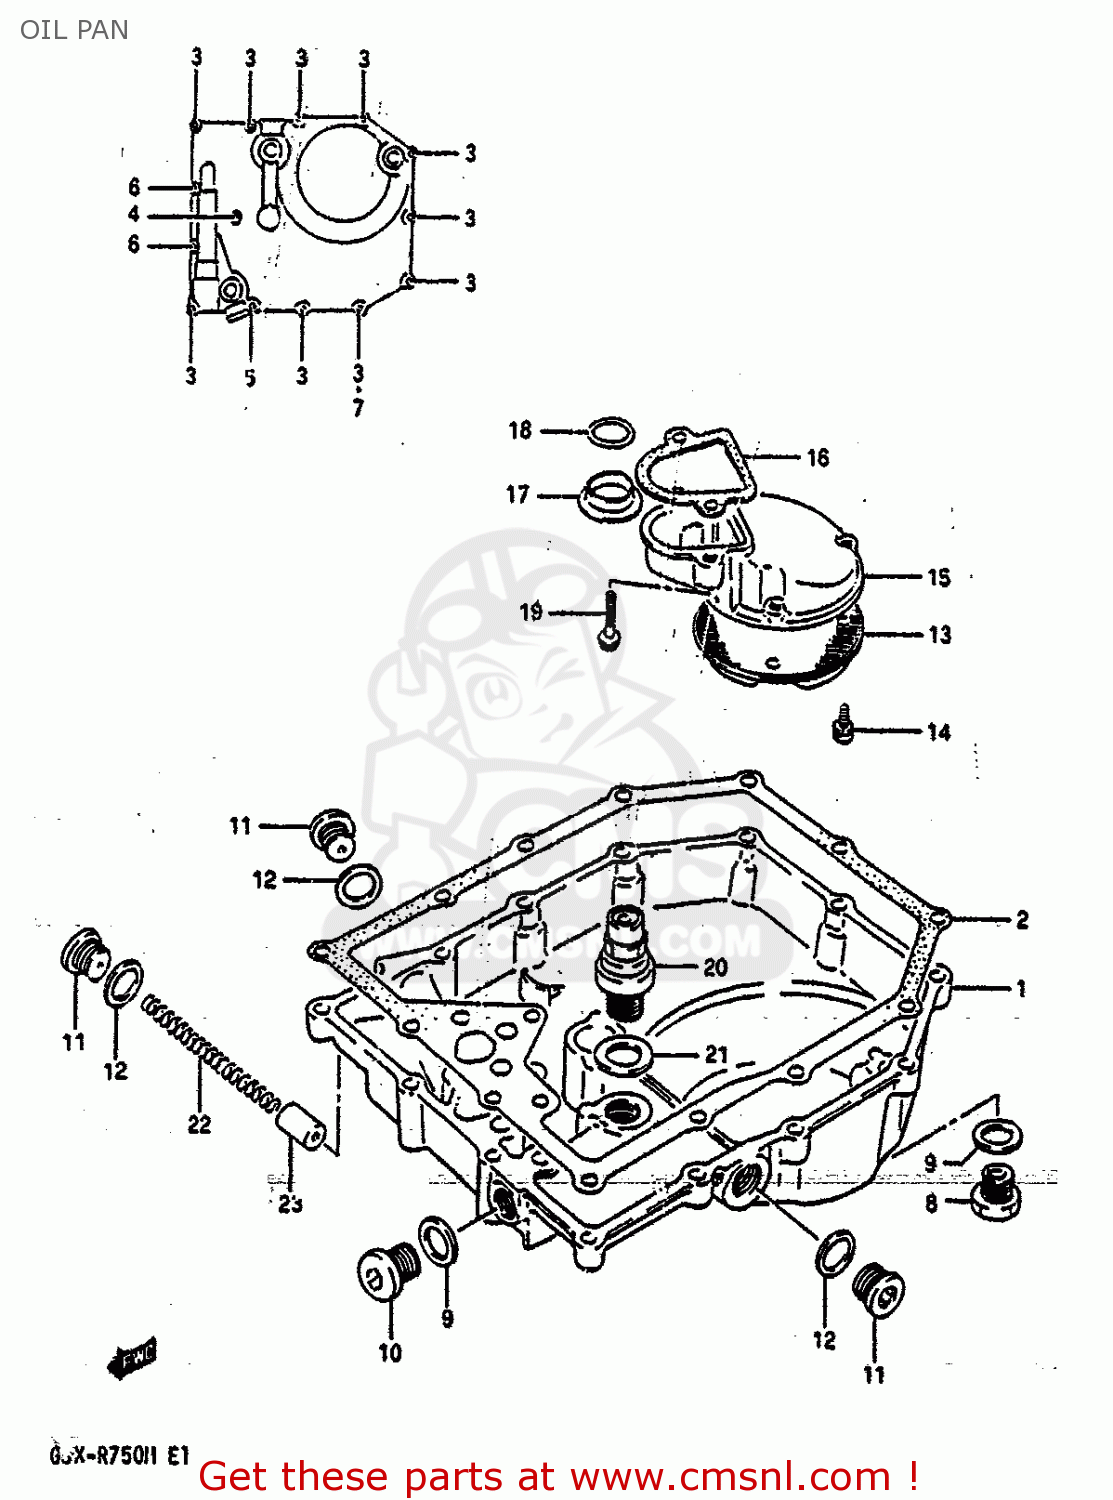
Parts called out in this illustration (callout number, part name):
1	PAN,OIL
2	GASKET,OIL PAN (NAS)
3	BOLT
4	BOLT
5	BOLT
6	BOLT
7	GASKET(5.8X11X1.2) (NAS)
8	PLUG
9	GASKET(14X19.2X2) (NAS)
10	PLUG,14X12
11	PLUG
12	GASKET(16X22X2) (NAS)
13	STRAINER,ENGINE OIL
14	BOLT
15	PROTECTOR,OIL STRAINER
16	O-RING
17	GASKET,OIL OUTLET (NAS)
18	O RING(D:3.2,ID:17.8)
19	BOLT 6X25
20	VALVE ASSEMBLY,OIL RELIEF
21	GASKET(16X22X2) (NAS)
22	SPRING
23	PLUNGER,OIL CONTROLL
